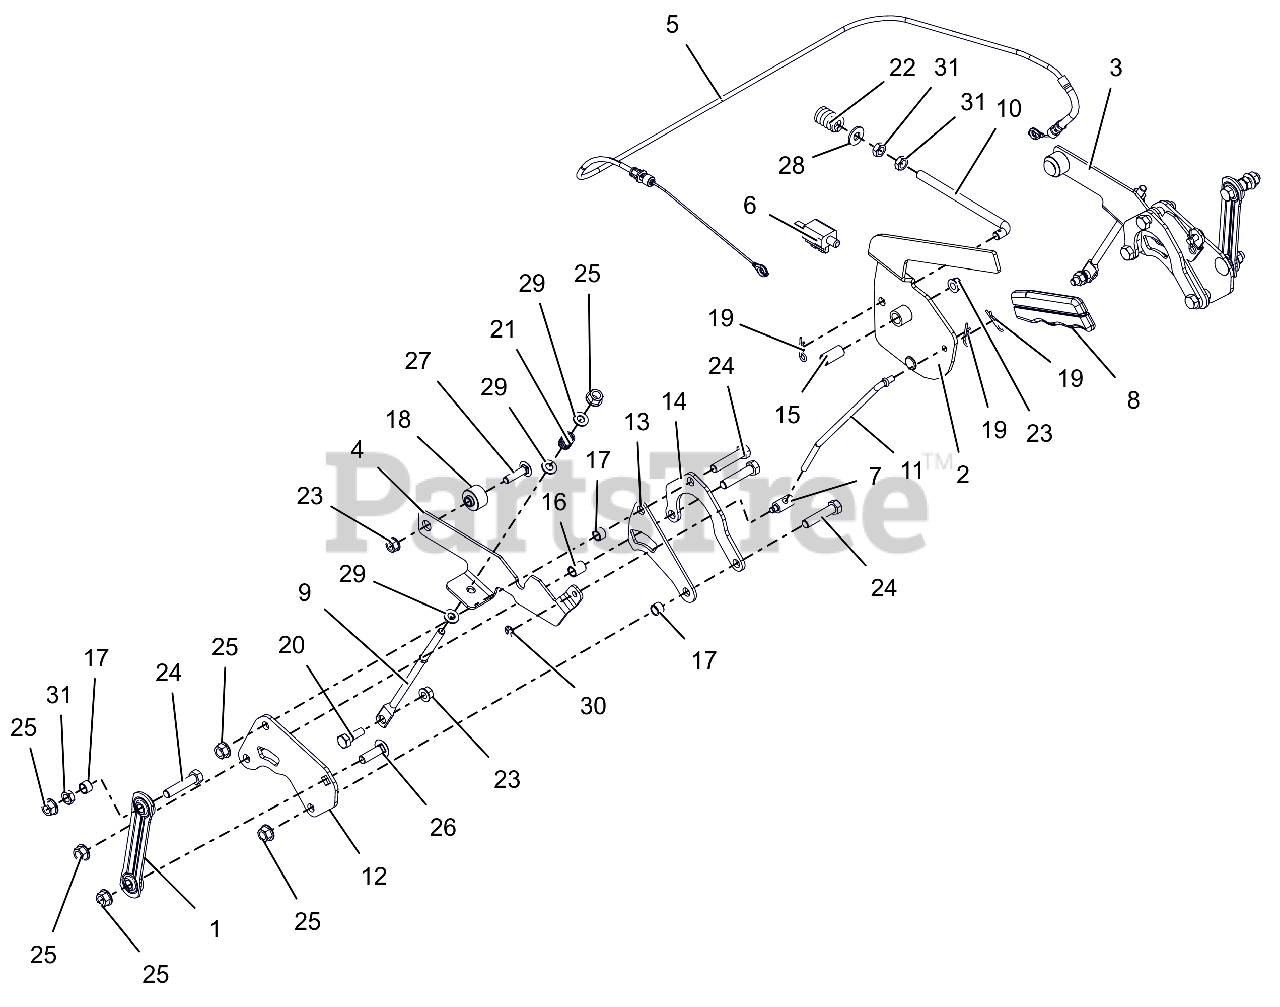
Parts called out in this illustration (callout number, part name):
1	LINK, STAMPED STEERING
2	LEVER, PARKING BRAKE
3	ARM, BRAKE - LH (W/PIN)
4	ARM, BRAKE-RH
5	CABLE, BRAKE - PARKING
6	SWITCH, SINGLE POLE N.O.
7	TRUNION, 1/4-20
8	GRIP, PARKING BRAKE (YELLOW)
9	ROD, LINK - TRANSMISSION BRAKE
10	ROD, OVER CENTER
11	ROD, BRAKE LINK
12	BRKT, TRANSAXLE STEERING
13	BRKT-SPACER
14	PLATE, REAR REINFORCING
15	BSHG-SLV .385X.500X1.045
16	SPCR, SLV .385X.500X.652
17	SPCR, SLV .385X.500X.350
18	SPCR, FLANGE
19	PIN, HAIR #213 .08X1.19 ZCC
20	BOLT,SHLDR .38X.25 -.31-18X.75
21	SPRING, COMPRESSION
22	SG-COMP .187X.56X1.62
23	NUT-LK-TOP-FLG .312-18 GF ZCC
24	BLT, HEX .38-16X1.75 G5 ZCC
25	NUT-LK-TOP-FLG .38-16 ZC120
26	BLT,RHSSN .38-16X1.25 G5 ZCC
27	BTL,RHSSN .313-18 X 1.25 G5 ZCC
28	WSHR,FLT .375X.875X.083 ZCC
29	WSHR,FLT .344X.688X.065 ZCC
30	RG-RTNG-EXT .250X.025
31	NUT-JAM .375-16 G2 ZCC
